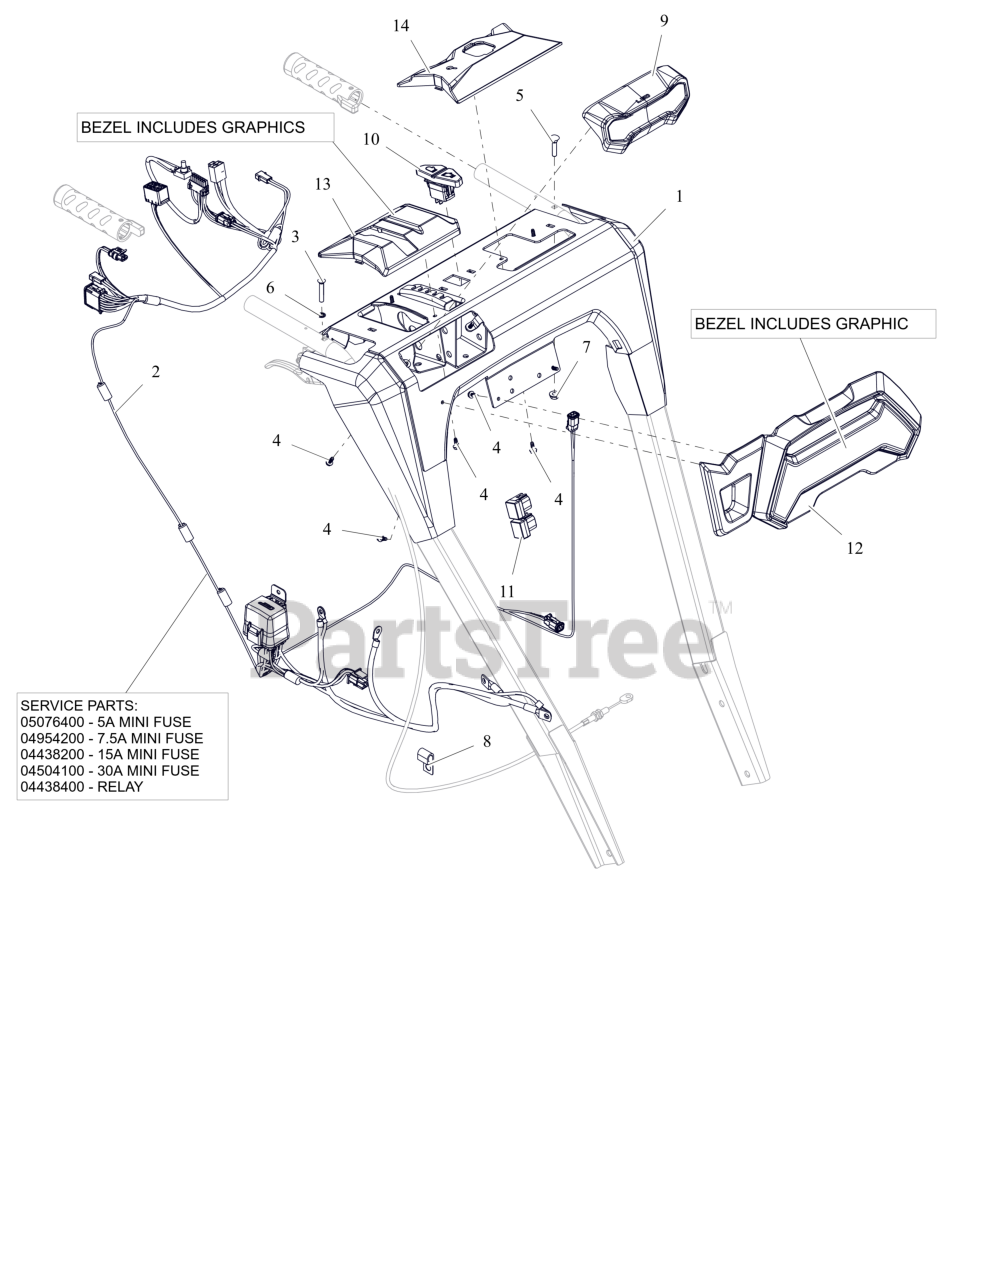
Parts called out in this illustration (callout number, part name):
1	PANEL, DASH HYDRO EFI ECR TRACK
2	HARNESS-WIRE-12V LT HG
2	FUSE, 5 AMP MINI-ATC
2	FUSE, 7.5 AMP MINI-ATC
2	Fuse, 15 AMP MINI-ATC
2	FUSE,30 AMP MINI-ATC
2	RELAY,MICRO5 TERML W/RESISTOR
3	SCR,OVAL .25-20X1.50 ZCC
4	SCR, PLASTIC #10X.50
5	BLT-RDHDXLSQNK.25-20X1.25 G5ZC
6	WSHR-LK-INT .250 TH TYA
7	NUT-LK-CTR-FLG .25-20 ZC120
8	J-CLAMP
9	HEADLIGHT ASM- LED
10	SWITCH- ROCKER SPST-ON/OFF
11	PACK, DIODE
12	BEZEL- LARGE - PROFESSIONAL
13	BEZEL, SHIFT HYDRO TRACK DECAL
14	BEZEL, OPERATOR EFI DECAL
